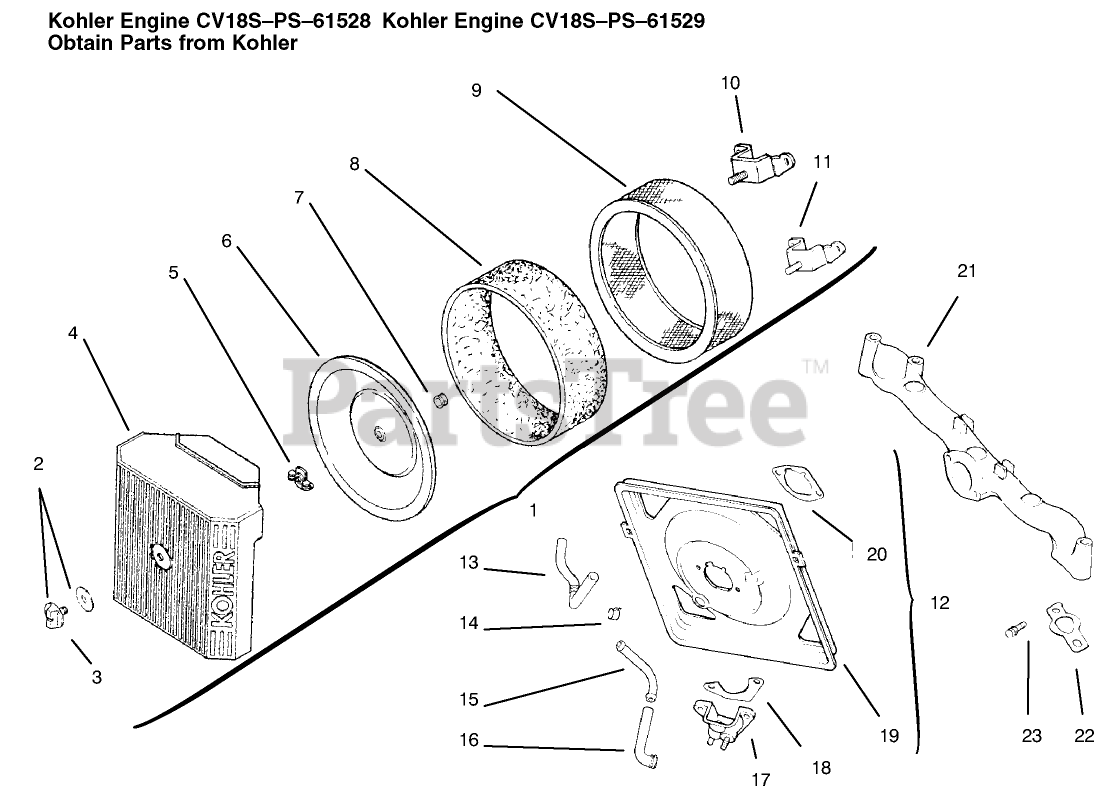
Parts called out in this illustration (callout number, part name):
1	Kit-Air Cleaner Cover
2	Kit-Knob w/Gasket
3	Knob-Cover
4	Cover-Air Cleaner
5	Nut-Wing
6	Cover-Inner Air Cleaner
7	Seal-Air Intake (Only On: 72103)
8	Element-Precleaner
9	Element-Air Cleaner
10	Bracket-Air Cleaner
11	Bracket-Air Cleaner
12	Kit-Air Cleaner Base
13	Hose-Breather
14	Clamp
15	Fitting
16	Hose-Breather
17	Cup-Fuel Spitback
18	Gasket-Fuel Spitback Cup (Only On: 72103, 72083)
19	Base-Air Cleaner
20	Gasket-A/C Base (Only On: 72103, 72083)
21	Manifold-Intake (Only On: 72103)
22	Gasket-Intake Manifold
